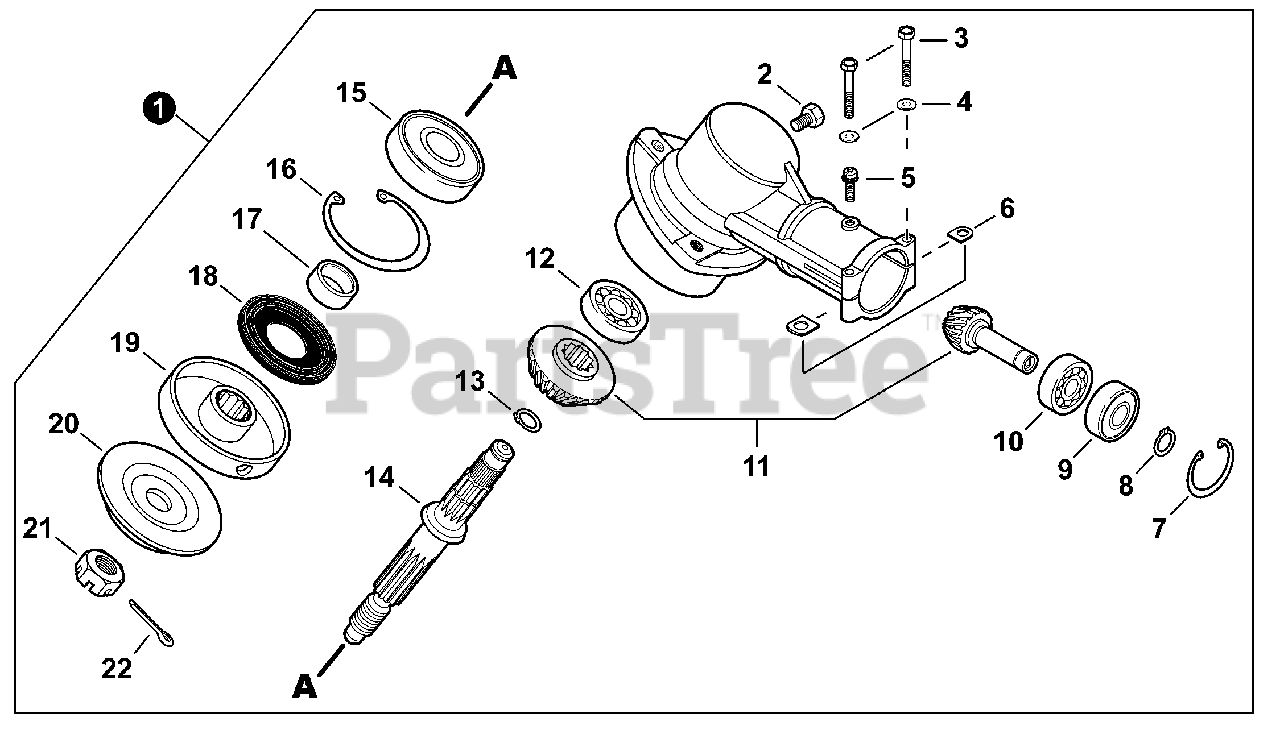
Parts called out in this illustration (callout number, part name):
1	GEAR CASE ASSY
2	BOLT M8×8
3	BOLT 5×35 SP
4	WASHER, FLAT 5.5×10×0.8
5	SCREW 5×10
6	D-WASHER
7	RING, SNAP 22
8	RING, SNAP 10
9	BEARING, BALL 6900-Z
10	BEARING, BALL 6900
11	GEAR SET
12	BEARING, BALL 609
13	RING, SNAP 12
14	SHAFT, GEAR
15	BEARING, BALL 6201
16	RING, SNAP 32
17	SPACER 11.8×15×9
18	SEAL, OIL 22
19	PLATE, ADAPTOR - UPPER
20	PLATE, ADAPTOR - LOWER
21	NUT 10×1.25 LH
22	PIN, COTTER 2×22
